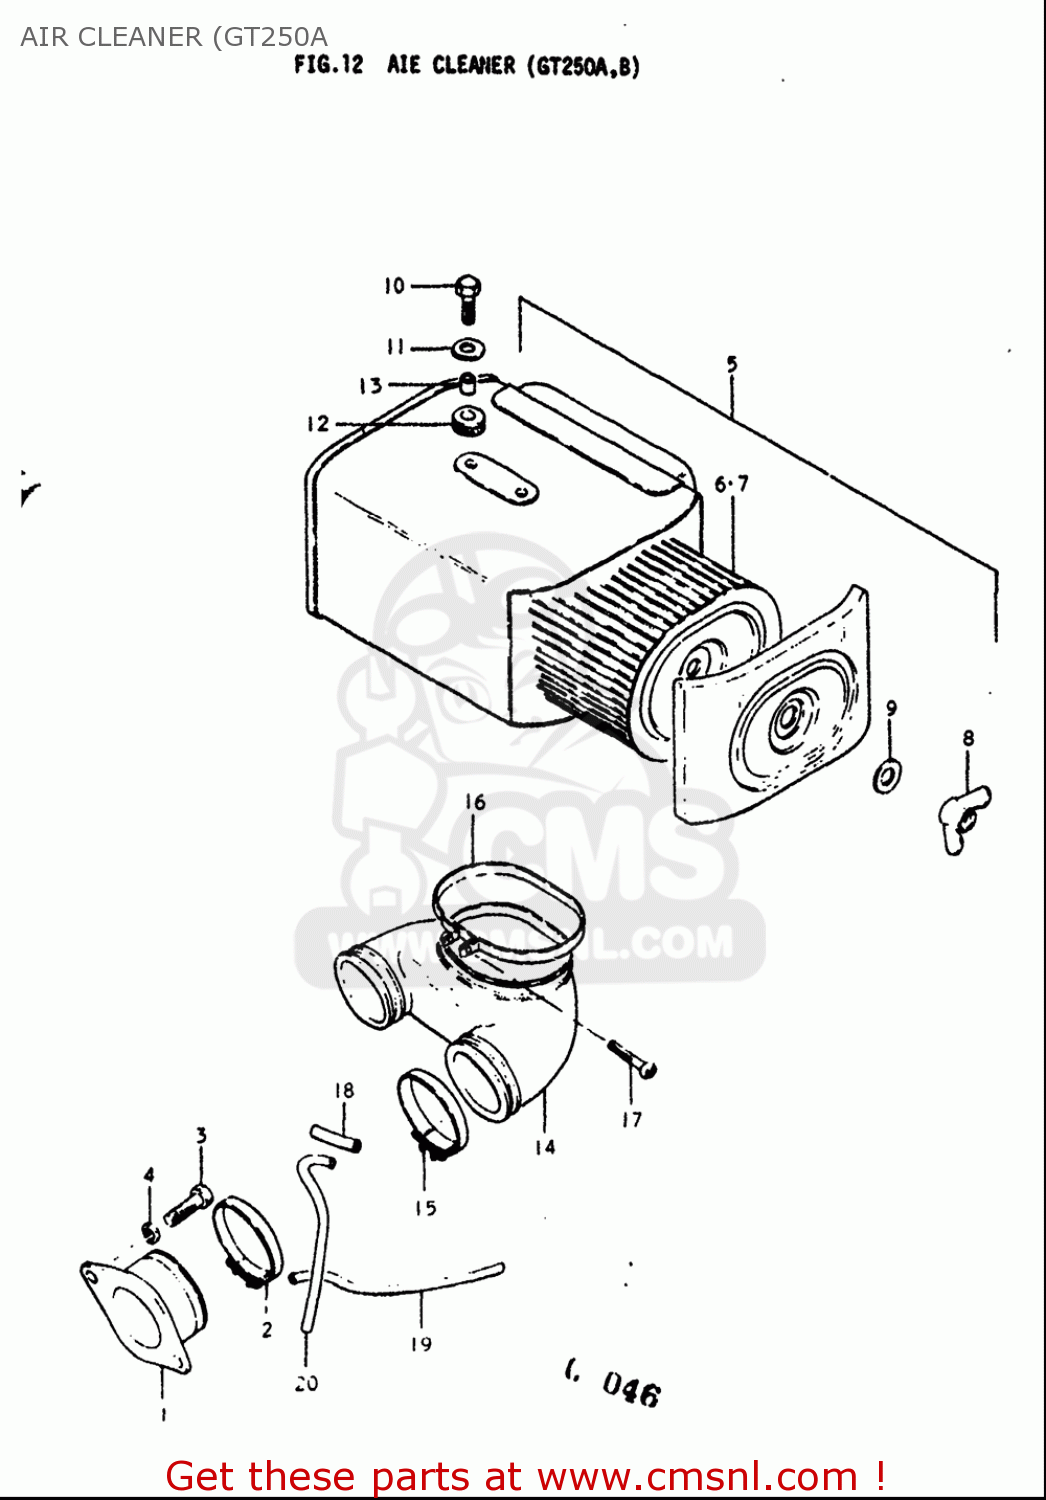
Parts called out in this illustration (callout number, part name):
1	PIPE,INTAKE
2	CLAMP
4	WASHER,LOCK
6	FILTER ASSY,AIR CLEANER
7	FILTER
8	NUT
9	WASHER
10	BOLT
11	WASHER(6.5X20X1.2)
12	CUSHION
13	SPACER,6.5X9X7
14	HOSE,CARBURETOR AIR INLET
15	CLAMP
16	CLAMP
17	SCREW
18	HOSE(6X10X600)
19	HOSE(3X5X600)
